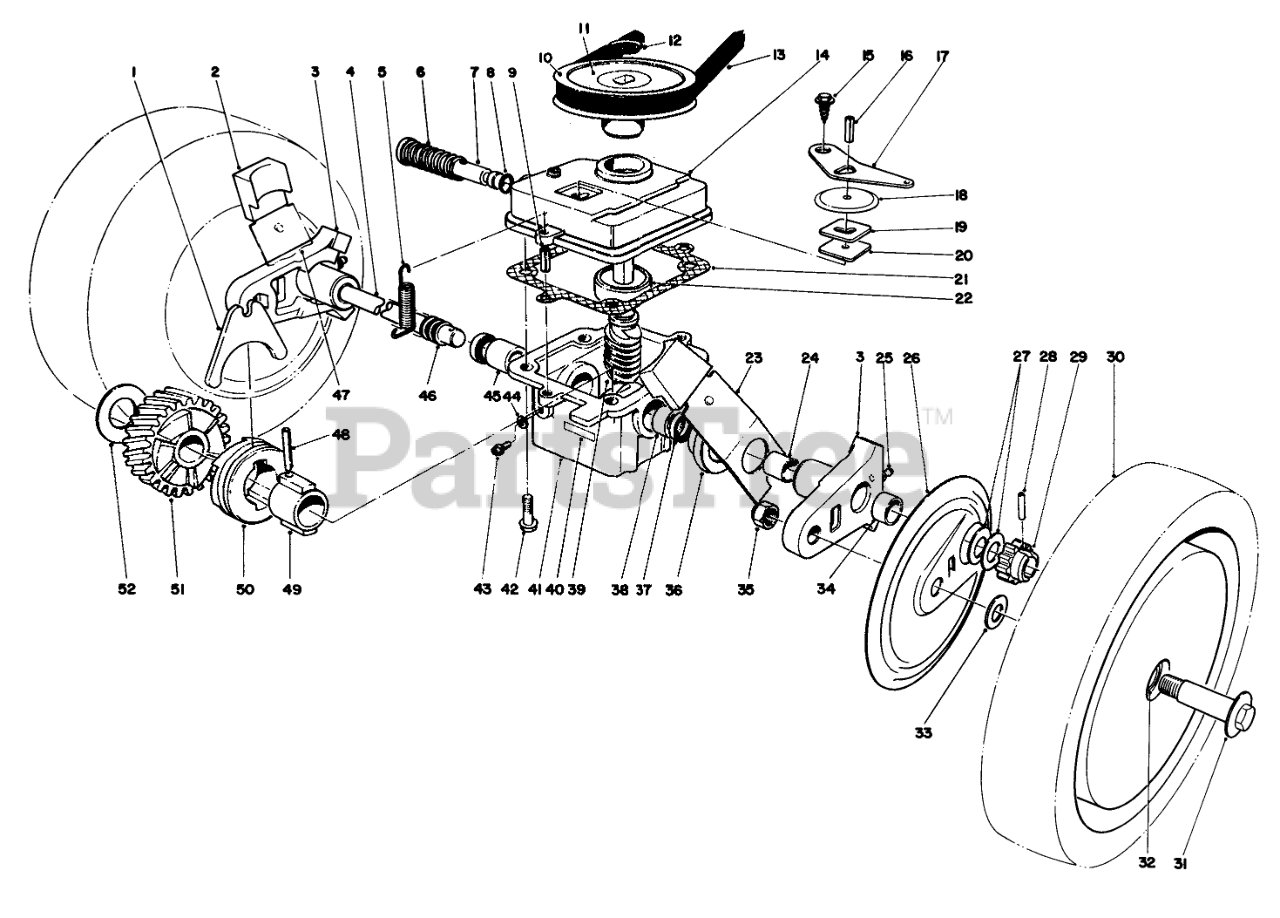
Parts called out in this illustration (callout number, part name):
1	SHIFTER FORK
2	KNOB-ARM
3	Pivot Arm (Incl. Ref. #24. 25 & 34)
4	DRIVE SHAFT (SERVCE)
5	TENSION SPRING
6	SPRING
7	SHIFTER ROD
8	O-RING
9	3/16 X 1/2 ROLL PIN
10	PULLEY
11	DECAL
12	PUSH-ON 93-3236
13	V BELT
14	GEAR CASE COVER
15	Screw
16	SPIROL PIN H D
17	SHIFTER ARM
18	DUST COVER
19	LATCH PLATE
20	DUST FILTER
21	GASKET
22	BEARING
23	SPRING ARM ASM SP LH
24	BUSHING
25	FITTING-GREASE
26	WHEEL COVER
27	THRUST WASHER
28	Pin
29	PINION GEAR 14T
30	Wheel & Tire Assembly (Incl. Ref. #32)(used on units with serial no. 7001848 & up)
31	WHEEL BOLT
32	BUSHING
33	WASHER
34	BUSHING
35	Nut
36	CAP-END
37	SEAL-OIL
38	BUSHING
39	Worm Shaft & Gear (Incl. Ref. #51)
40	DECAL
41	Gear Case (Incl. Ref. #37, 38 & 45)
42	Screw
43	NYLON SCREW
44	FILL PLUG GASKET
45	BUSHING
46	COVER-SHAFT, DRIVE
47	SPRING ARM ASM SP RH
48	COIL PIN
49	SLEEVE
50	CLUTCH JAW
51	Helical Gear
52	THRUST WASHER
